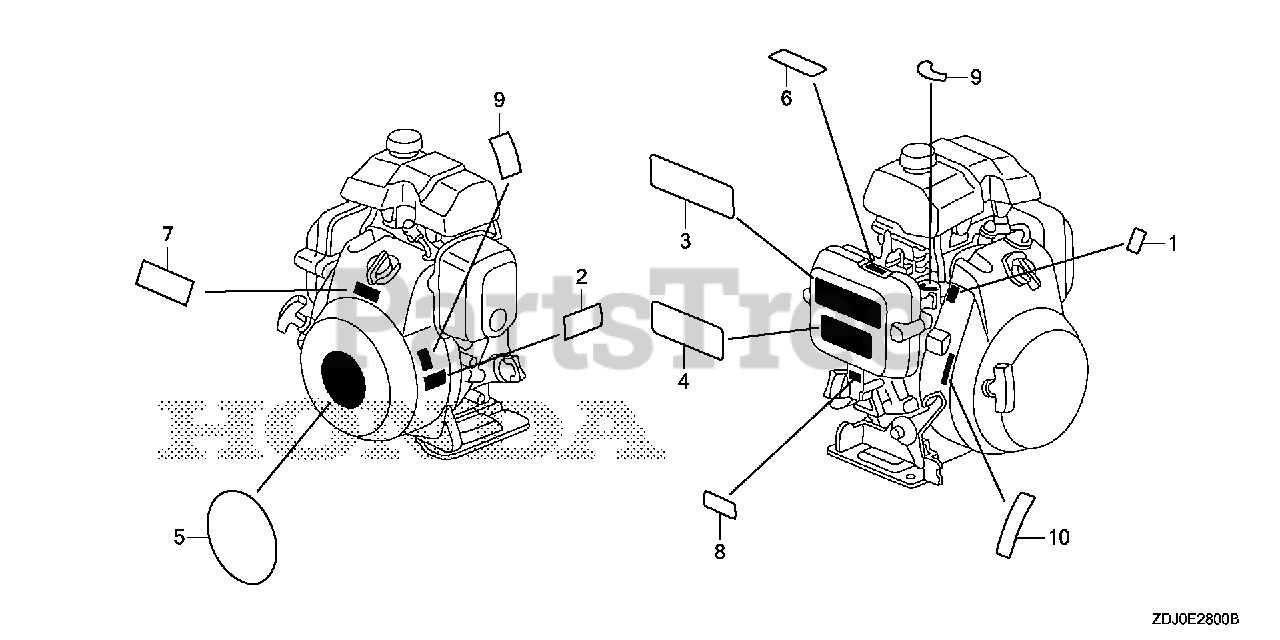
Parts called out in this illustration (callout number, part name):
3	MARK, OPERATOR CAUTION (PICTOGRAPH)
6	MARK, CHOKE INDICATION
8	MARK, TYPE (KRWB)
